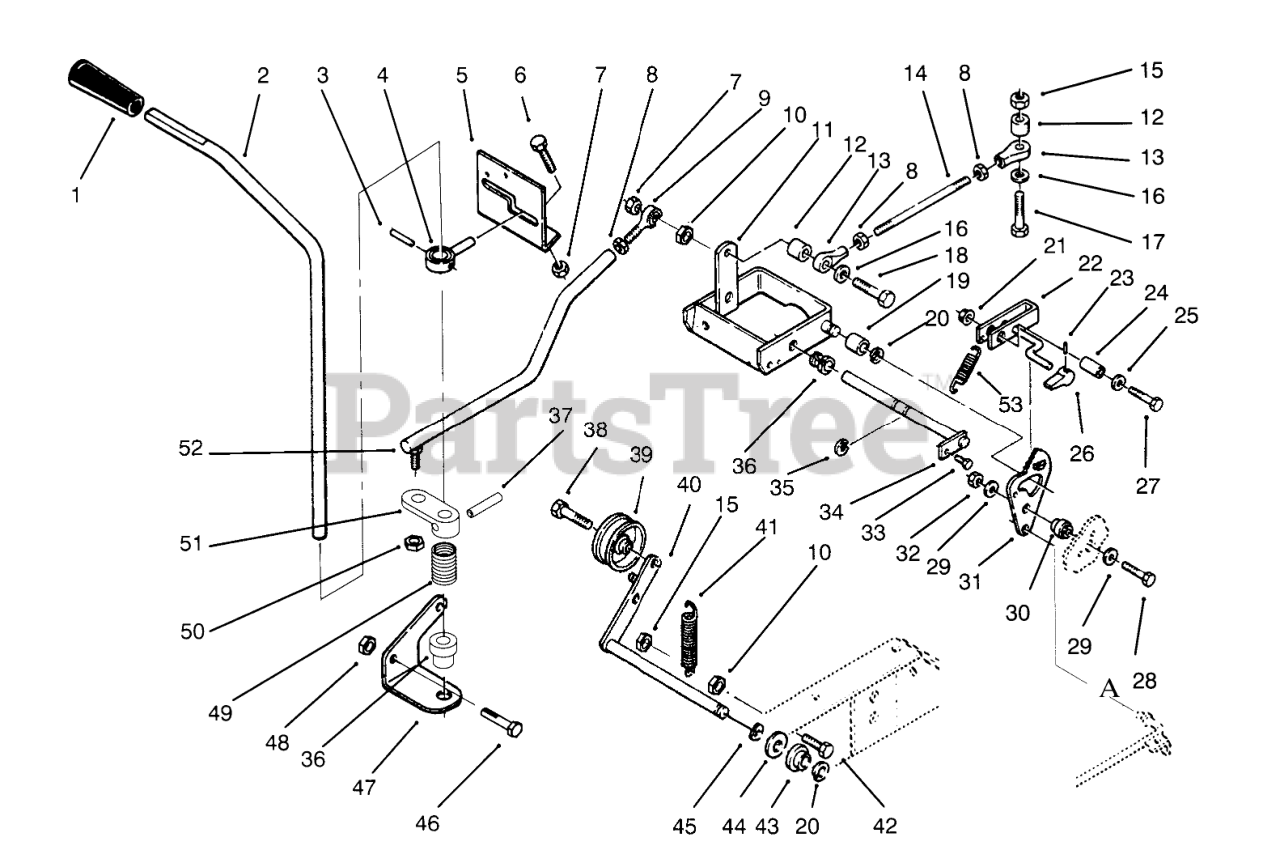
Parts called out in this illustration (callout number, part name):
1	Knob-Motion Control
2	ROD-MOTION CONTROL
3	SPIROL PIN 7/32X7/8
4	GUIDE-CONTROL
5	Bracket-Control
6	SCREW-HH
7	NUT-LOCK, NI
8	NUT-JAM
9	ROD END, 1/4-28
10	NUT-HEX
11	Cam Comtrol
12	Spacer
13	ASSY ROD END
14	ROD-CONTROL
15	NUT-LOCK
16	WASHER-FLAT
17	SCREW-HH
18	HHCS 1/4X2.25 FULL T
19	BEARING-CAM RETURN
20	RING-RETAINING, EXTERNAL
21	LOCKNUT-FLANGE
22	Lever-Parking Brake
23	PIN-SPIROL 3/32X5/8
24	SPACER
25	WASHER-SPACER
27	SCREW-HH
28	SCREW-HH
29	WASHER-FLAT
30	Spacer
31	Cam Plate
32	NUT-LOCK, NI
33	SCREW
34	ASSY-ROD CAM PIVOT
35	RING-RETAINING, EXTERNAL
36	NYLINER BUSHING
37	Pin-Spirol
38	SCREW-HH
39	PULLEY-IDLER
40	WLDMT-IDLER ARM
41	SPRING-EXTENSION
42	SCREW-HH
43	BUSHING-FLANGED
44	SHIM-WASHER
45	CURVED-SPRING WASHER
46	SCREW-HH
47	Bracket-Control
48	NUT-LOCK, NI
49	Spring
50	NUT-LOCK
51	ARM-CONTROL
52	ASSY-ROD & BALL JOINT
53	EXTENSION-SPRING
